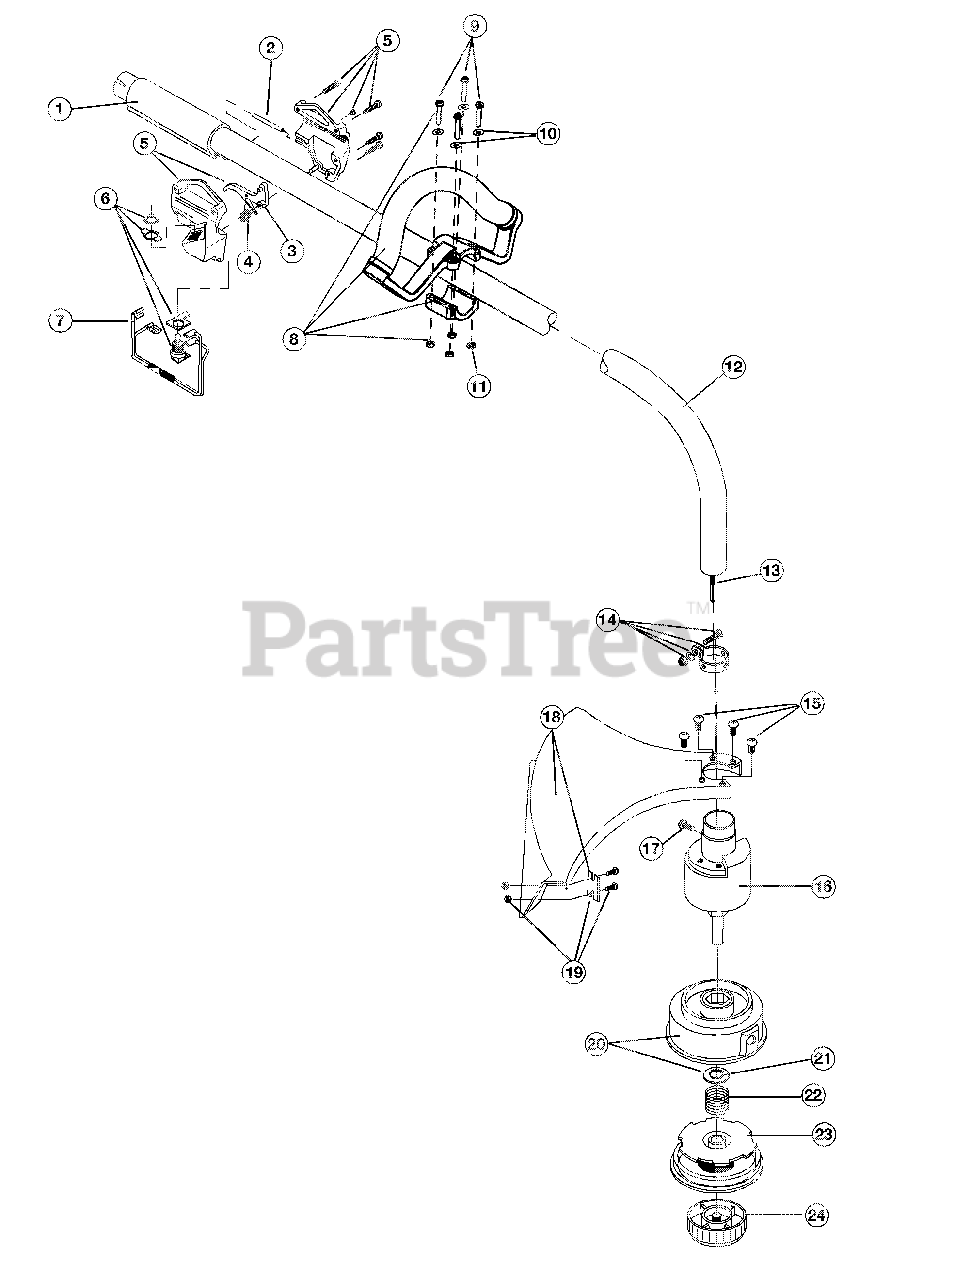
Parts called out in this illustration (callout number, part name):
2	Throttle Cable Assembly
3	Throttle Trigger
4	Throttle Trigger Spring
5	Throttle Trigger Assembly
6	Switch Assembly
7	Wire Lead Assembly
8	Loop Handle Assembly
11	Nut
12	Drive Shaft Housing Assembly
13	Flexible Drive Shaft
14	Lower Clamp Assembly
15	Shield Mounting Screw
16	Bushing Housing Assembly
17	Anti-Rotation Screw
18	Shield and Blade Assembly
19	Blade Assembly
20	Outer Spool w/ Retainer
23	Inner Reel
24	Bump Knob Assembly
